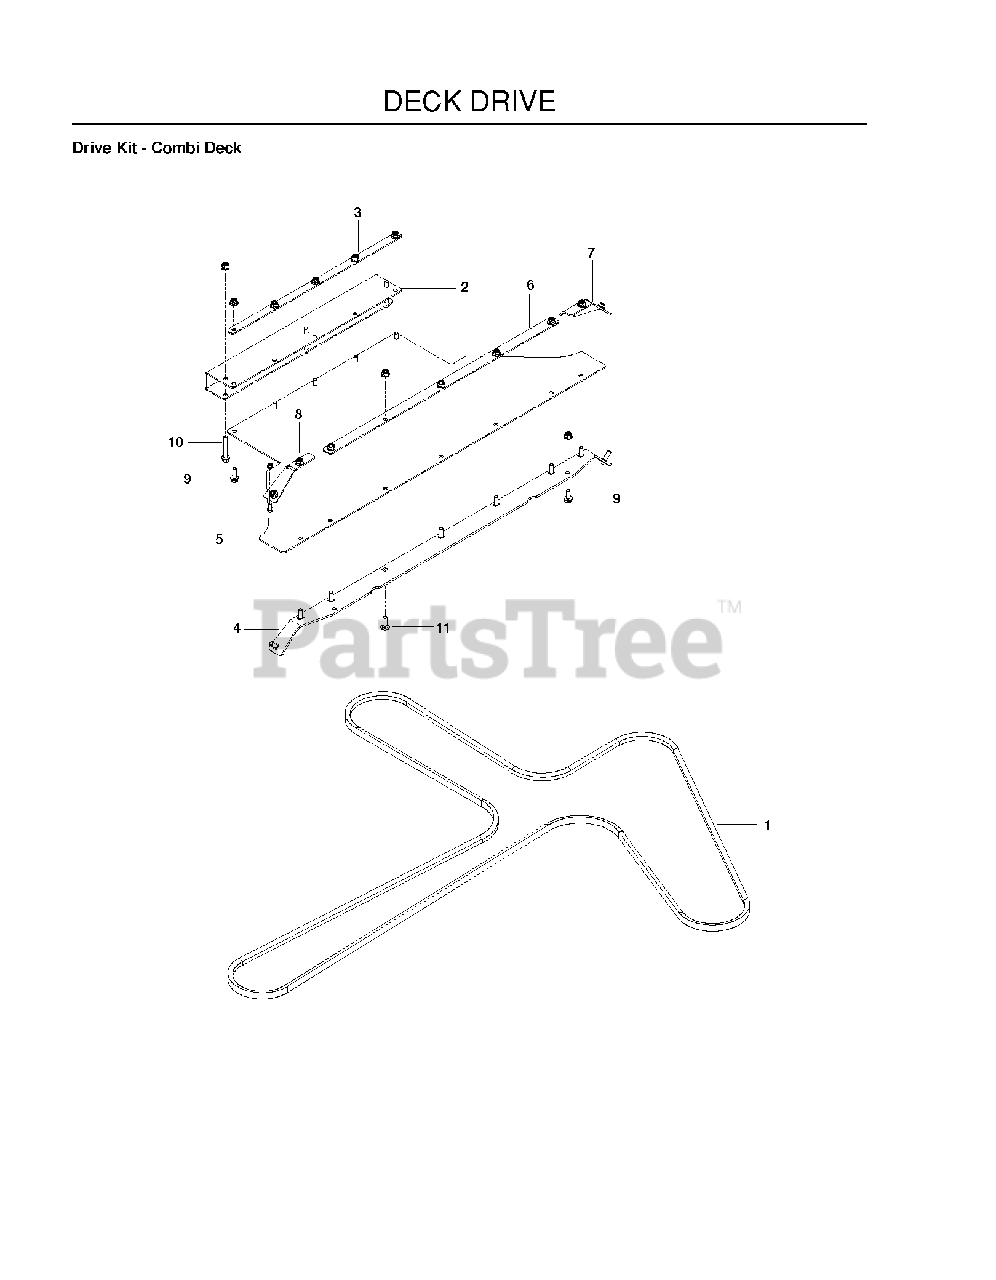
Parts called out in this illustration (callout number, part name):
1	BELT, "5V", 180"
2	CHANNEL, MTG BLACK
3	STRAP, SHORT BLACK
4	PLATE, MTG BLACK
5	GUARD, RUBBER 61C
6	STRAP, LONG BLACK
7	BRKT, L.H. CORNER BLK
8	BRKT, R.H. CORNER BLK
9	HHFS 5/16-18 X 3/4
10	HHFS 5/16-18 X 2.25 GD 5
11	RHSNB 5/16C X 1
